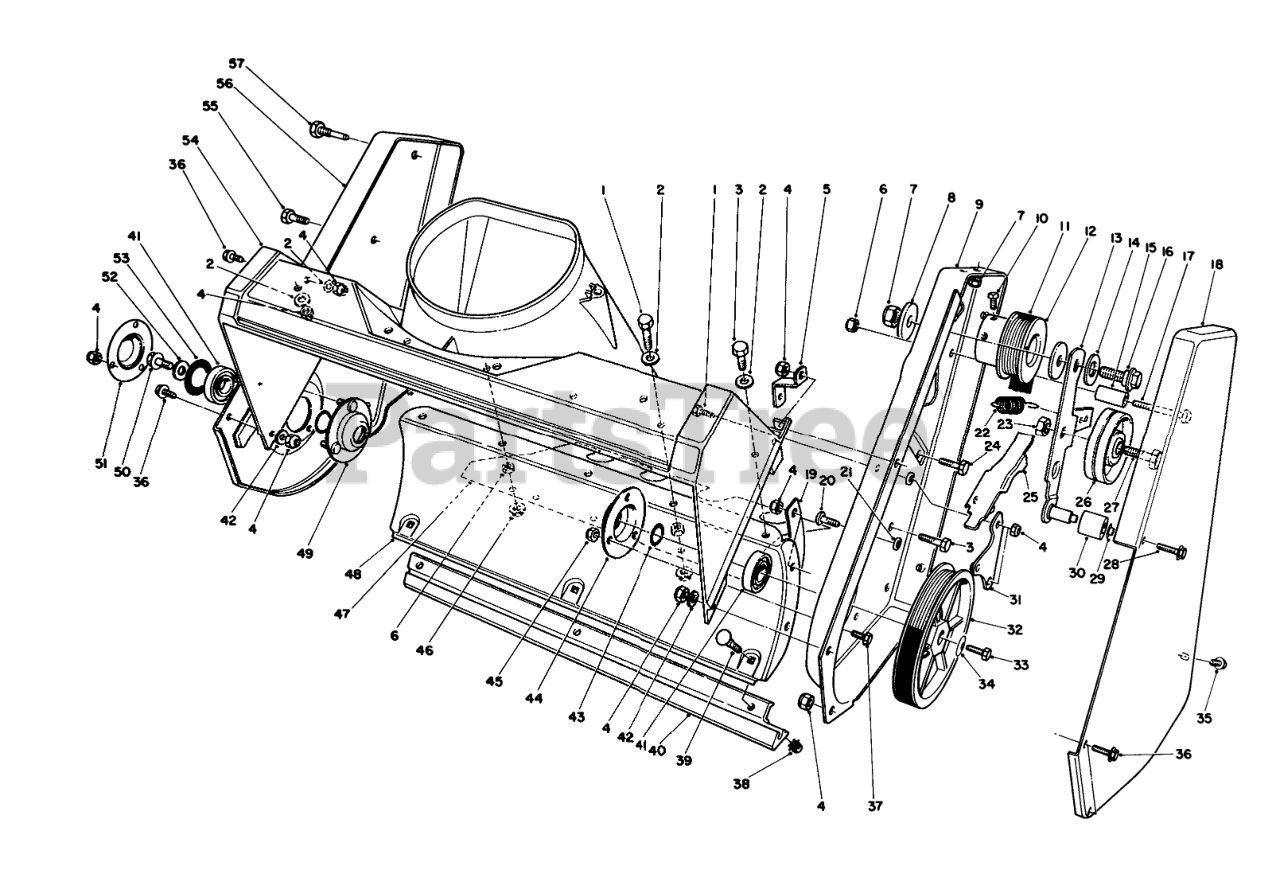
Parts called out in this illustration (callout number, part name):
1	SCREW-HH
2	WASHER-FLAT
3	SCREW-HH
4	NUT-LOCK, NI
5	BRACKET-HOUSING
6	NUT-HEX, SIDE DEFORM
7	NUT-LOCK, NI
8	WASHER-PIVOT
9	Sideplate-L.H.
10	SCREW-SQH
11	BELT - DRIVE
12	ENGINE PULLEY
13	Idler Arm Assembly
14	WASHER
15	SLEEVE-GUIDE, BELT
16	SCREW-SHOULDER
17	SCREW-HH
18	Cover-Drive
19	LOWER HSG BRKT
20	SCREW-HSBH
21	SPACER-PLATE, PIVOT
22	SPRING-EXTENSION
23	NUT-LOCK, CONE
24	SCREW-HH
25	BRAKE-ARM
26	PULLEY-IDLER
27	SCREW-HH
28	SCREW-HWH, TAP
29	NUT-PUSH
30	ROLLER-BRAKE
31	PIVOT PLATE ASM
32	Pulley-Rotor
33	SCREW-HH
34	WASHER-BELLEVILLE
35	SCREW
36	SCREW-HWH
37	SCREW-SHH
38	NUT-KEPS
39	SCREW-CARR
40	SCRAPER
41	BEARING-BALL
42	WASHER-FLAT
43	WASHER-THRUST
44	FLANGE-BEARING
45	NUT-LOCK, NI
46	NUT-LOCK, HHF
47	Cover-Bottom
48	Housing-Lower
49	FLANGE-BEARING
50	SCREW-HHF
51	Trough
52	WASHER-FLAT
53	WASHER-RUBBER
54	HOUSING
55	SCREW-HH
56	Sideplate-RH
57	PIN-ROTOR
